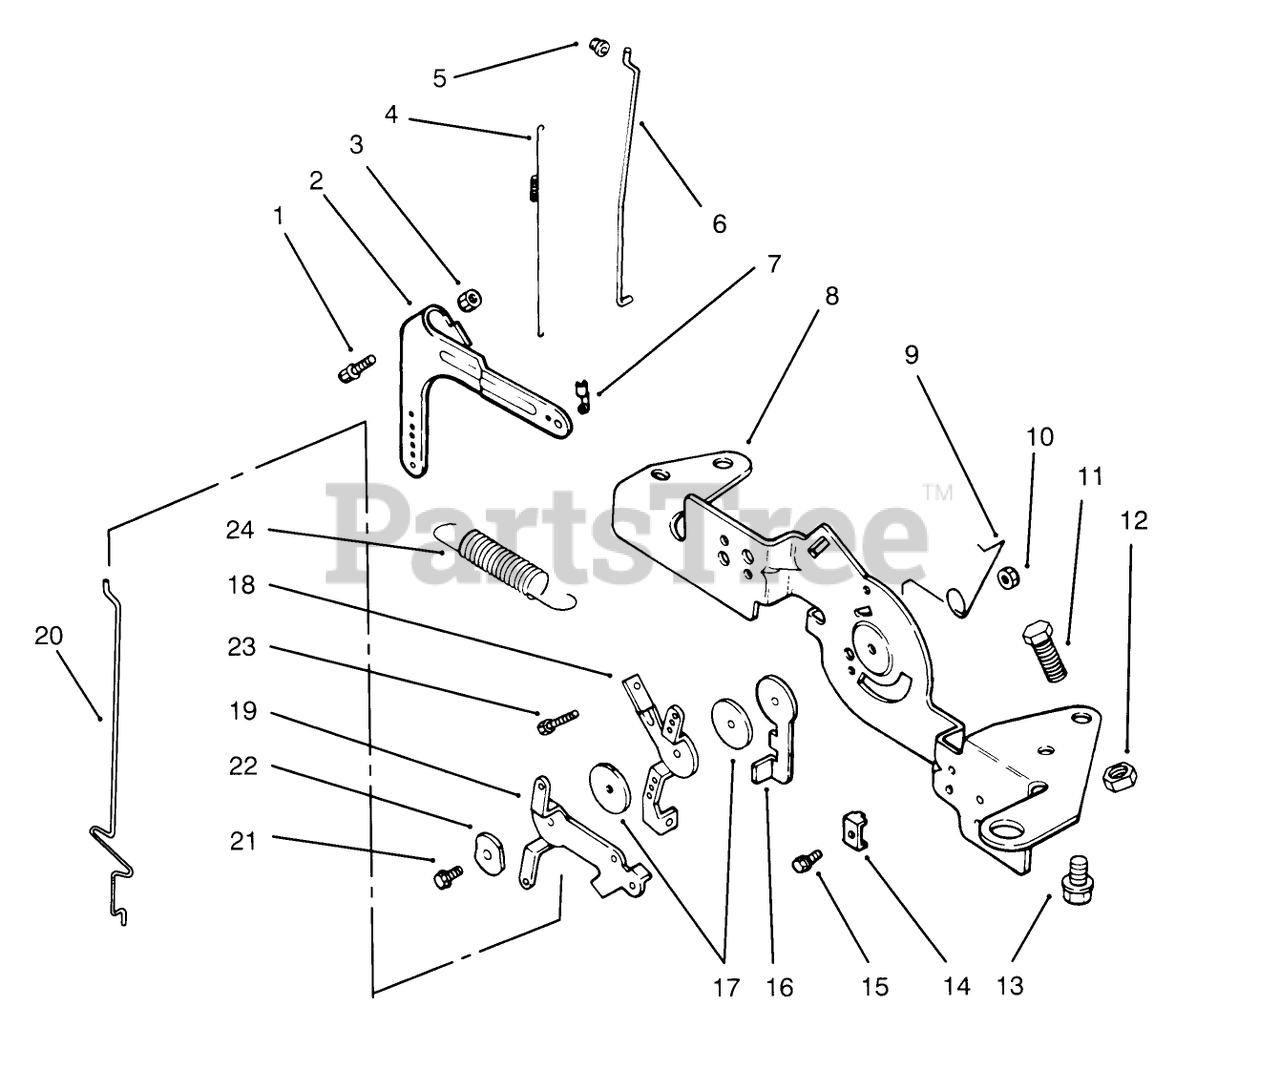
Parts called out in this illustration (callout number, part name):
2	Lever-Governor (Only On: 72103)
4	Spring-Linkage
5	Bushing
6	Linkage-Throttle (Only On: 72103)
7	Bushing-Linkage
8	Bracket-Control
9	Spring-Choke Return
16	Lever-Throttle Actuator
18	Lever-Throttle Control
19	Lever-Choke
20	Linkage-Choke (Only On: 72103, 72083)
22	Washer-Wave
24	Spring-Governor
